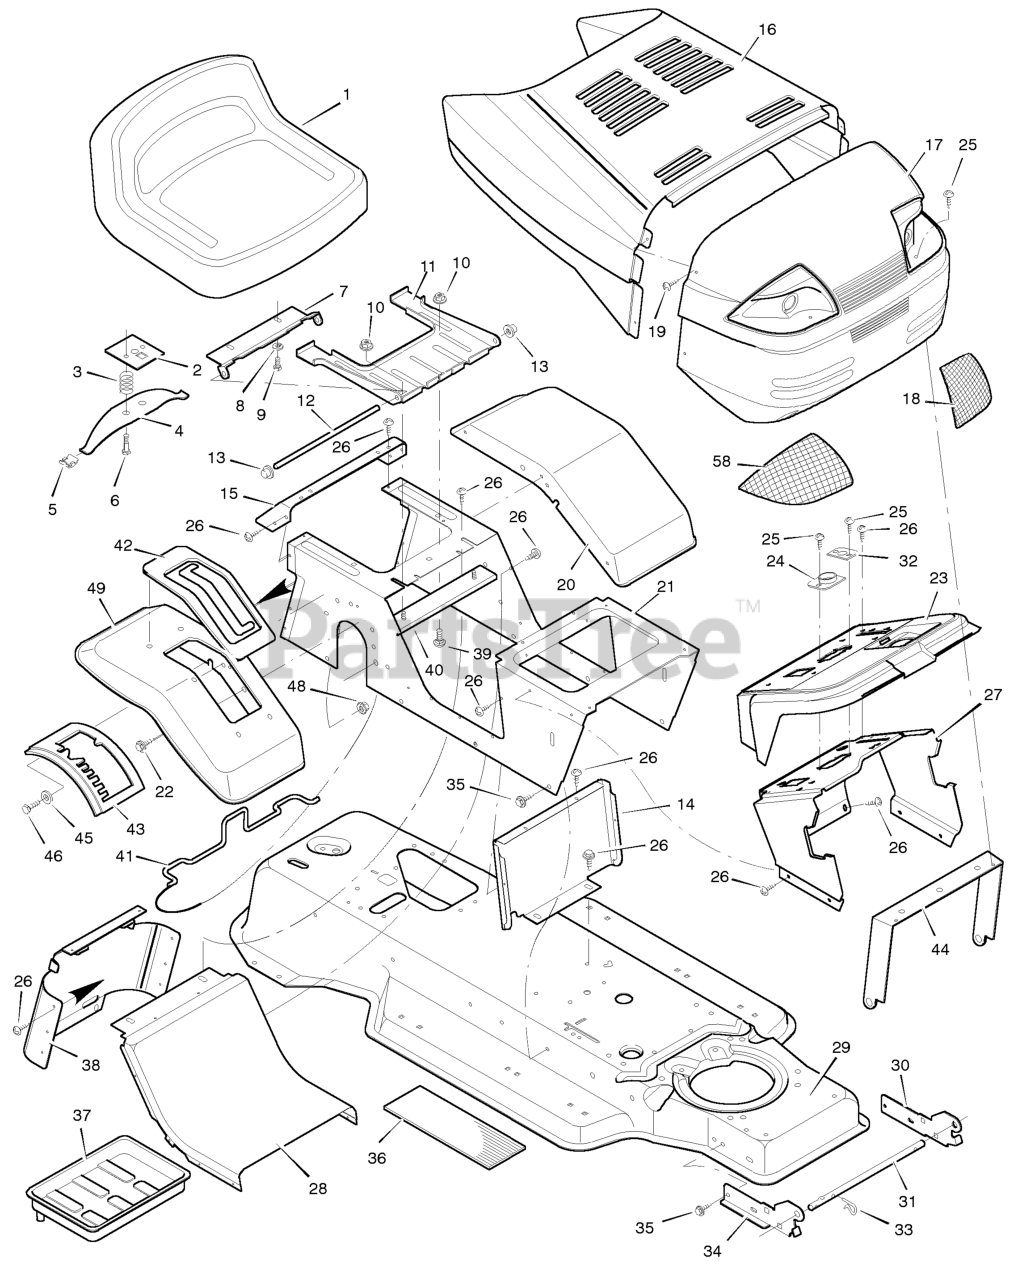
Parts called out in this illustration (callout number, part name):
2	Plate Assembly, Switch
3	Spring, Compression
4	Spring, Seat
5	Glide, Spring
6	Bolt, Shoulder
7	Support, Seat
8	Lockwasher
9	Bolt, Hex
10	Locknut, Flange
11	Bracket, Pivot
12	Rod, Pivot
13	Cap, Push On
14	Insert, Front
15	Fender, Apron
17	Grille Assembly
18	Lens, Left
21	Console Assembly
23	Dash Panel
24	Bearing, Steering
26	Screw
27	Support, Dash
28	Insert, Rear
29	Frame Assembly
30	Bracket, Left Grille
31	Rod, Pivot
32	Bearing
33	Pin, Hair
34	Bracket, Right Grille
37	Tray, Battery
38	Cap, Console
39	Bolt
40	Channel Assembly
41	Clamp, Battery
42	Cover, Shift
43	Gate, Shift
44	Brace, Grille
46	Bolt, Hex
48	Locknut
49	Fender, SOG
58	Lens, Right
